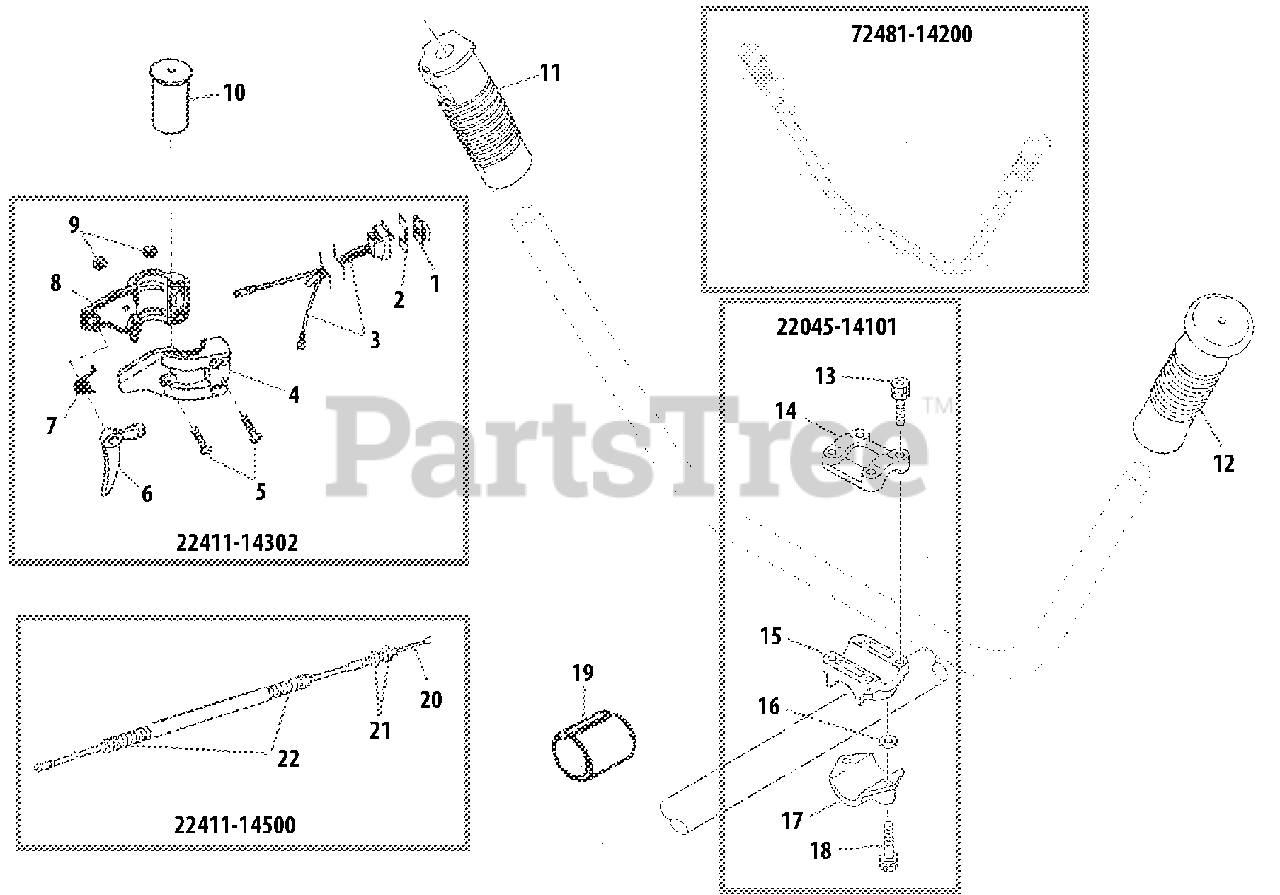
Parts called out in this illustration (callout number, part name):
1	KNOB, SWITCH
2	PLATE, SWITCH
3	SWITCH, ON-OFF
4	CONTROL HANDLE - LEFT
5	SCREW
6	TRIGGER, THROTTLE
7	SPRING, RETURN
8	CONTROL HANDLE - RIGHT
9	NUT M5
10	SPACER
11	GRIP, THROTTLE
12	GRIP
13	BOLT M5×25
14	CLAMP - UPPER
15	BRACKET
16	WASHER, FLAT 5.5×10×0.8
17	CLAMP - LOWER
18	BOLT M5×25
19	SPACER
20	CABLE, THROTTLE
21	NUT M6
22	TUBE, PLASTIC PROTECTIVE
22045-14101	HANDLE BRACKET KIT
22411-14302	THROTTLE CONTROL ASSY
22411-14500	CABLE ASSY, THROTTLE
72481-14200	HANDLEBAR ASSY
